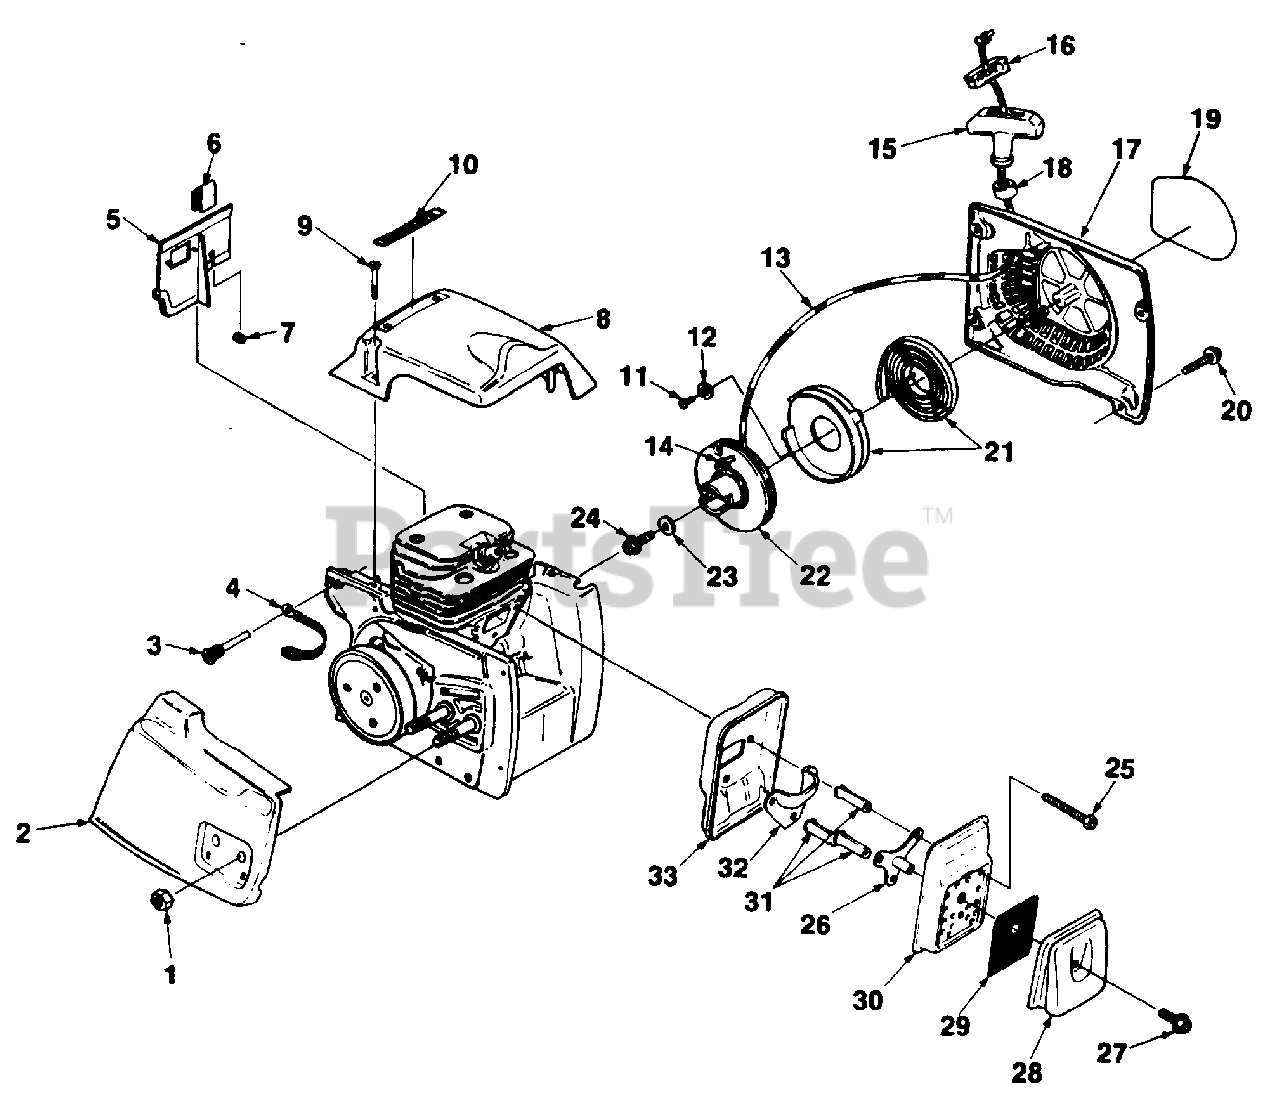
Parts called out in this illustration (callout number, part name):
1	NUT- 3/8-16
2	COVER- Drivecase
3	PIN- Isolator
4	STRAP- Ground
5	DEFLECTOR- Air
6	CLIP- Spring
7	GROMMET
8	COVER- Cylinder
9	SCREW- Cylinder cover
10	LABEL- Homelite
11	SCREW- Plastite
12	WASHER- Flat
13	ROPE- Starter
14	WASHER
15	GRIP- Starter
16	INSERT- Rope retaining
17	HOUSING- Starter
18	BUSHING
20	SCREW
21	RETAINER & SPRING
22	CUP & PULLEY
23	WASHER- Retaining
24	SCREW- Thd. retaining
25	SCREW- Mach. hex hd.
26	SPACER & PLATE KIT
27	SCREW- 10-24 x .375
28	CAP- Muffler
29	SCREEN- Spark arrestor
30	COVER- Muffler
31	SPACER- Muffler
32	PLATE- Stiffner
33	BODY- Muffler
